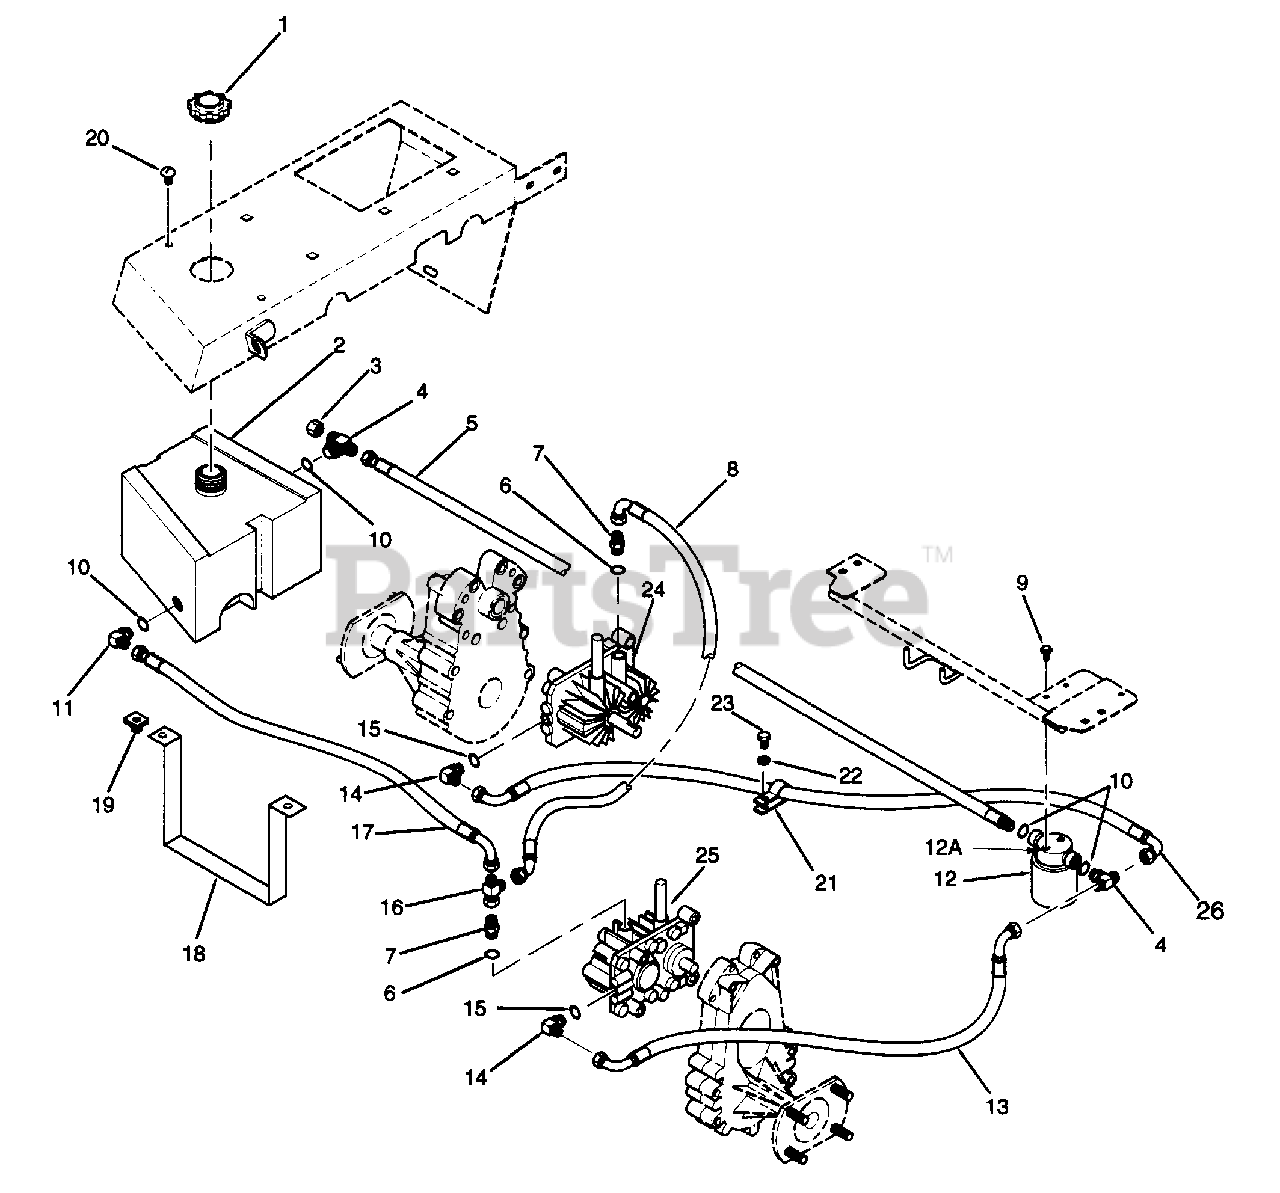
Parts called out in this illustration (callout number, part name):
1	CAP, HYDRAULIC RESERVOIR FILL
2	TANK, HYDRAULIC OIL
3	CAP, 3-4-16 JIC
4	TEE, 3/4-16 JIC X O-RING
5	HOSE ASSEMBLY, FILTER INLET
6	O-RING, 3/32 X 3/4 ID
7	UNION, TUBE
8	HOSE ASSEMBLY, CASE DRAIN
9	SERR. FL. HEX HEAD CPSCRW, 1/4-30 X 1/2
10	O-RING, 3/32 X 5/8 ID
11	ELBOW, 90DEG JIC TO O-RING
12	ELEMENT, FILTER
12A	HEAD, FILTER
13	HOSE ASSEMBLY, L.H. CHARGE PUMP
14	ELBOW, 90DEG 9/16-18 JIC TO 7/16-20 O-RING
15	O-RING, 1/16 X 3/8 ID
16	TEE, 3/4-16 SWIVEL
17	HOSE ASSEMBLY, CASE DRAIN RETURN
18	STRAP, HYDRAULIC TANK
20	MACHINE SCREW, ROUND HEAD, 1/4-20 X 2.00
21	CLAMP, CABLE
22	LOCKWASHER, 3/8
23	BOLT, HEX HEAD, 3/8-16 X 3/4
24	PUMP, R.H.
25	PUMP, L.H.
26	HOSE ASSEMBLY, RH CHARGE PUMP
